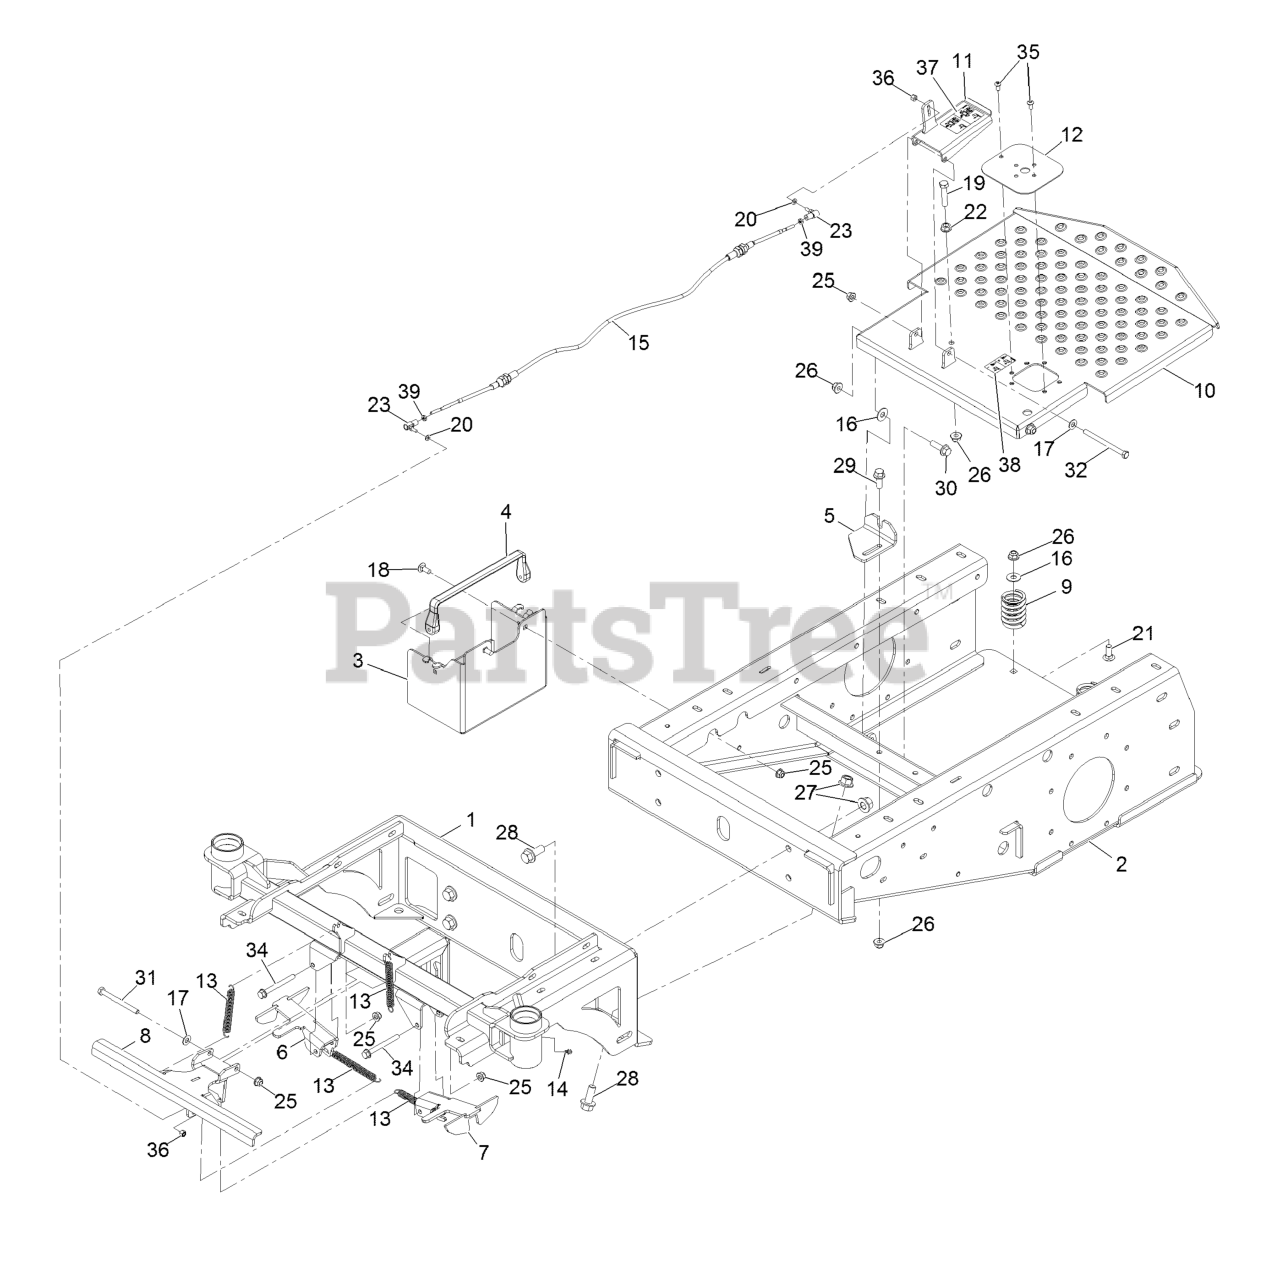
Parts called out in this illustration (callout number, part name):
1	Frame-Front
2	FRAME-REAR
3	BOX-BATTERY
4	BUNGEE (TARP STRAP)
5	Bracket, Lower Cable
6	Wing-Capture, Rt
7	Wing-Capture, Lt
8	Capture-Lcs
9	SPRING-COMPRESSION
10	PLATE-FOOT
11	Pedal-Foot
12	Panel, Foot Switch
13	SPRING-EXTENSION
14	FITTING-GREASE, ZERK
15	CABLE-CASTER, LOCKING
16	WASHER-FLAT
18	SCREW-CARR
19	Screw-HH
20	WASHER-FLAT
21	SCREW-CARR
22	Nut-Hex Flange
23	BALL JOINT-SS
25	Nut-Hex Flange
26	Nut-Hex Flange
27	NUT-HEX FLANGE
28	SCREW-HHF
29	SCREW-HHF
30	SCREW-HHF
31	SCREW-HH
32	Screw-HH
34	SCREW-HHF
35	Screw-HSBH
36	Nut,NYL Lock,#10-32,ST/ST 18-8
37	Decal-Lock, Caster
38	Decal-Spray Foot Button
39	Nut,Hex Jam Mch Scr,10-32,Sst
